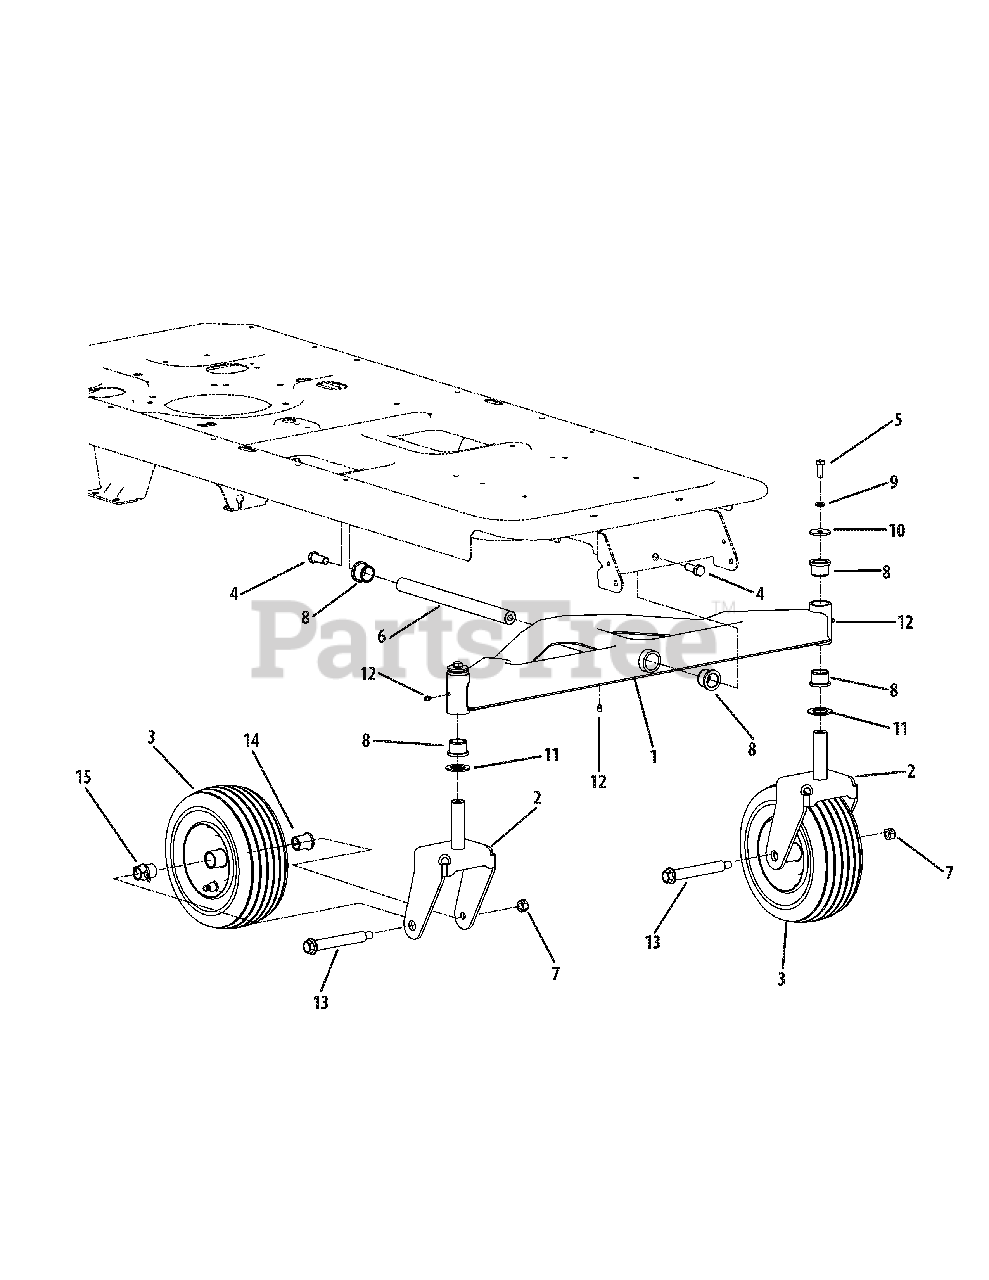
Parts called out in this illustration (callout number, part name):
1	Front Pivot Axle
2	Castor Wheel Bracket
3	Wheel Assembly, 11.0 x 4.0 x 5.0
4	Hex Lock Screw, 1/2-13 x 1.25
5	Hex Cap Screw, 3/8-16 x 1.0
6	Axle Shaft
7	Hex Lock Nut, 1/2-13
8	Flange Bearing, 1.0 x 1.246
9	Lock Washer, 3/8
10	Flat Washer, .39 x 1.5 x .134
11	Flat Washer, 1.0 x 1.75 x .107
12	Lube Fitting, 3/16 Drive
13	Shoulder Screw, 7/16-14 x .75 x 4.75
14	Flange Bearing, .76 x 1.0 x 1.2
15	Flange Bearing, .76 ID w/Lube Ftg.
